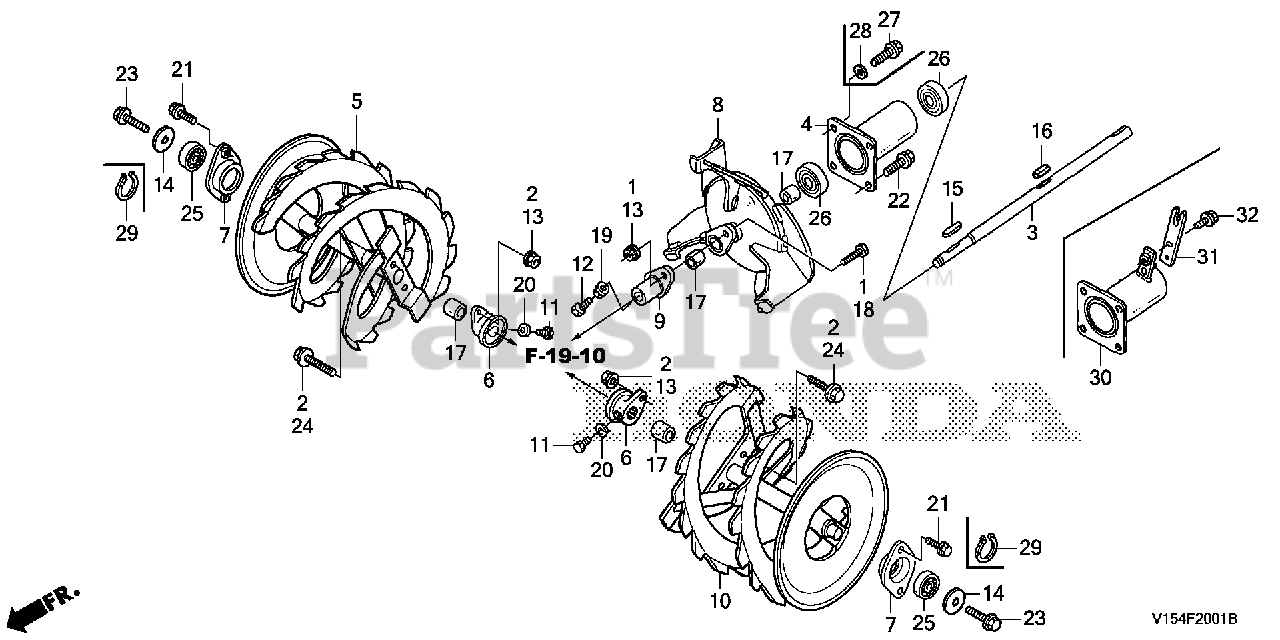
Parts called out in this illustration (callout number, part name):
1	BOLT SET, BLOWER
2	BOLT SET, AUGER
3	SHAFT, AUGER DRIVE
5	AUGER, R. (COO)
6	FLANGE, AUGER SHEAR
7	HOLDER, AUGER BEARING
9	PIPE, JOINT
11	BOLT, SPECIAL (10X16)
12	BOLT, SPECIAL (8X25)
13	NUT, SELF-LOCK (8MM)
15	KEY (6X6X40)
16	KEY (7X7X33)
17	BUSH (25X28X25)
18	BOLT, HEX. (8X25)
19	NUT, FLANGE (8MM)
20	WASHER, SPRING (10MM)
21	BOLT, FLANGE (8X12)
24	BOLT, FLANGE (8X25)
25	BEARING, RADIAL BALL (6004UU)
26	BEARING, RADIAL BALL (6205UU)
27	BOLT, FLANGE (8X20)
28	WASHER, PLAIN (8MM)
29	CIRCLIP (OUTER) (20MM)
30	HOLDER, BEARING
31	ARM, ROLLING SENSOR
32	BOLT, FLANGE (6X12) Use up to Engine SN 1543277.
